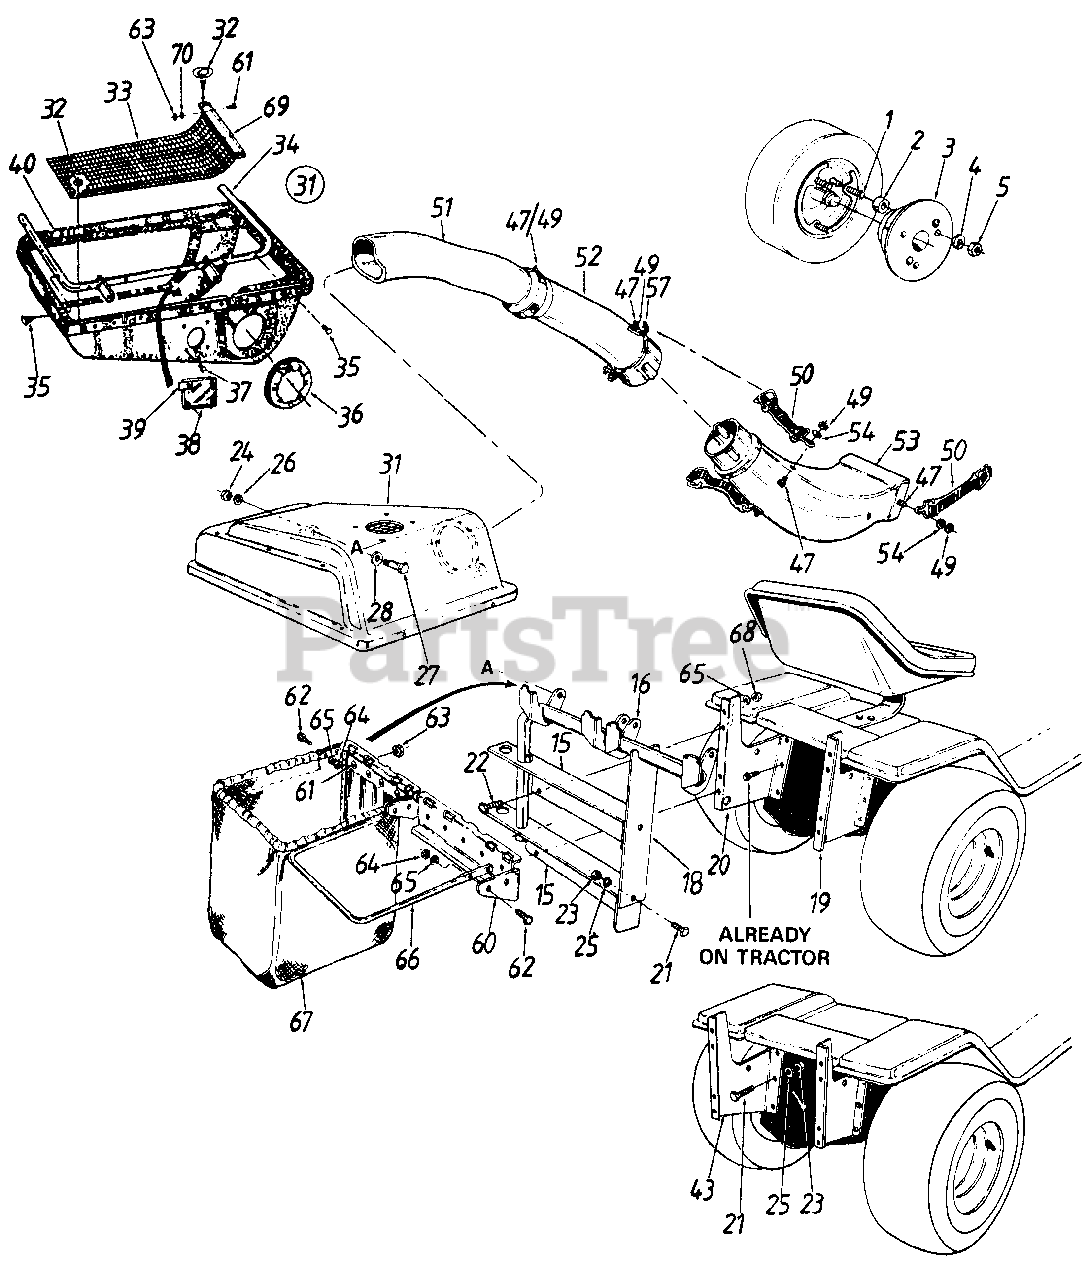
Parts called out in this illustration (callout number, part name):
1	Wheel Weight Snap Ring
3	Wheel Weight
4	Lock Washer 5/16" I.D.
5	Hex Nut 5/16-18 Thread
15	Catcher Support Tube Mtg. Brkt.
16	Catcher Support Tube Assy.
18	Catcher Latch and Support Brkt.
19	Grass Catcher Support Brkt.-R.H.
20	Grass Catcher Support Brkt.-L.H.
21	Hex Bolt 5/16-18 x .75" Lg.*
22	Hex Bolt 1/4-20 x .62" Lg.-Grade 5
23	Hex Nut 5/16-18 Thd.*
24	Hex Nut 3/8-16 Thd.
25	L.-Wash. 5/16" I.D.*
26	L.-Wash. 3/8" I.D.*
27	Shld. Bolt 3/8-16 x .500" Dia.
28	Bell.-Wash. .505" I.D. x 1.00" O.D.
31	Grass Catcher Cover Ass'y.
32	Twist Fastener
35	Hex Tap Scr. 1/4-20 x .5" Lg.
36	Seal
37	Truss Mach. B-Tap Scr. #10 0 x .5" Lg.
38	Plastic Plate
39	Speed Nut
40	Grass Catcher Cover
47	Hex Bolt 1/4-20 x .50" Lg.
49	Hex Ins. L.-Nut 1/4-20 0 Thd.
50	Retainer Strap Ass'y.
51	Catcher Elbow
52	Catcher Tube
53	Discharge Chute
54	L.-Wash. .27" I.D.
57	Retainer Hook Brkt.
61	Truss Mach. Scr. #10-24 0 x .50" Lg.
62	Hex Bolt 1/4-28 x .75" Lg.
63	Hex Sems Nut #10-24 0 Thd.
64	Hex Nut 1/4-28 Thd.*
65	L.-Wash. 1/4" I.D.*
67	Grass Catcher Bag
68	Hex Nut 1/4-20 Thd.*
69	Screen Mtg. Brkt.
70	Flat Wash. 1/4" I.D.
